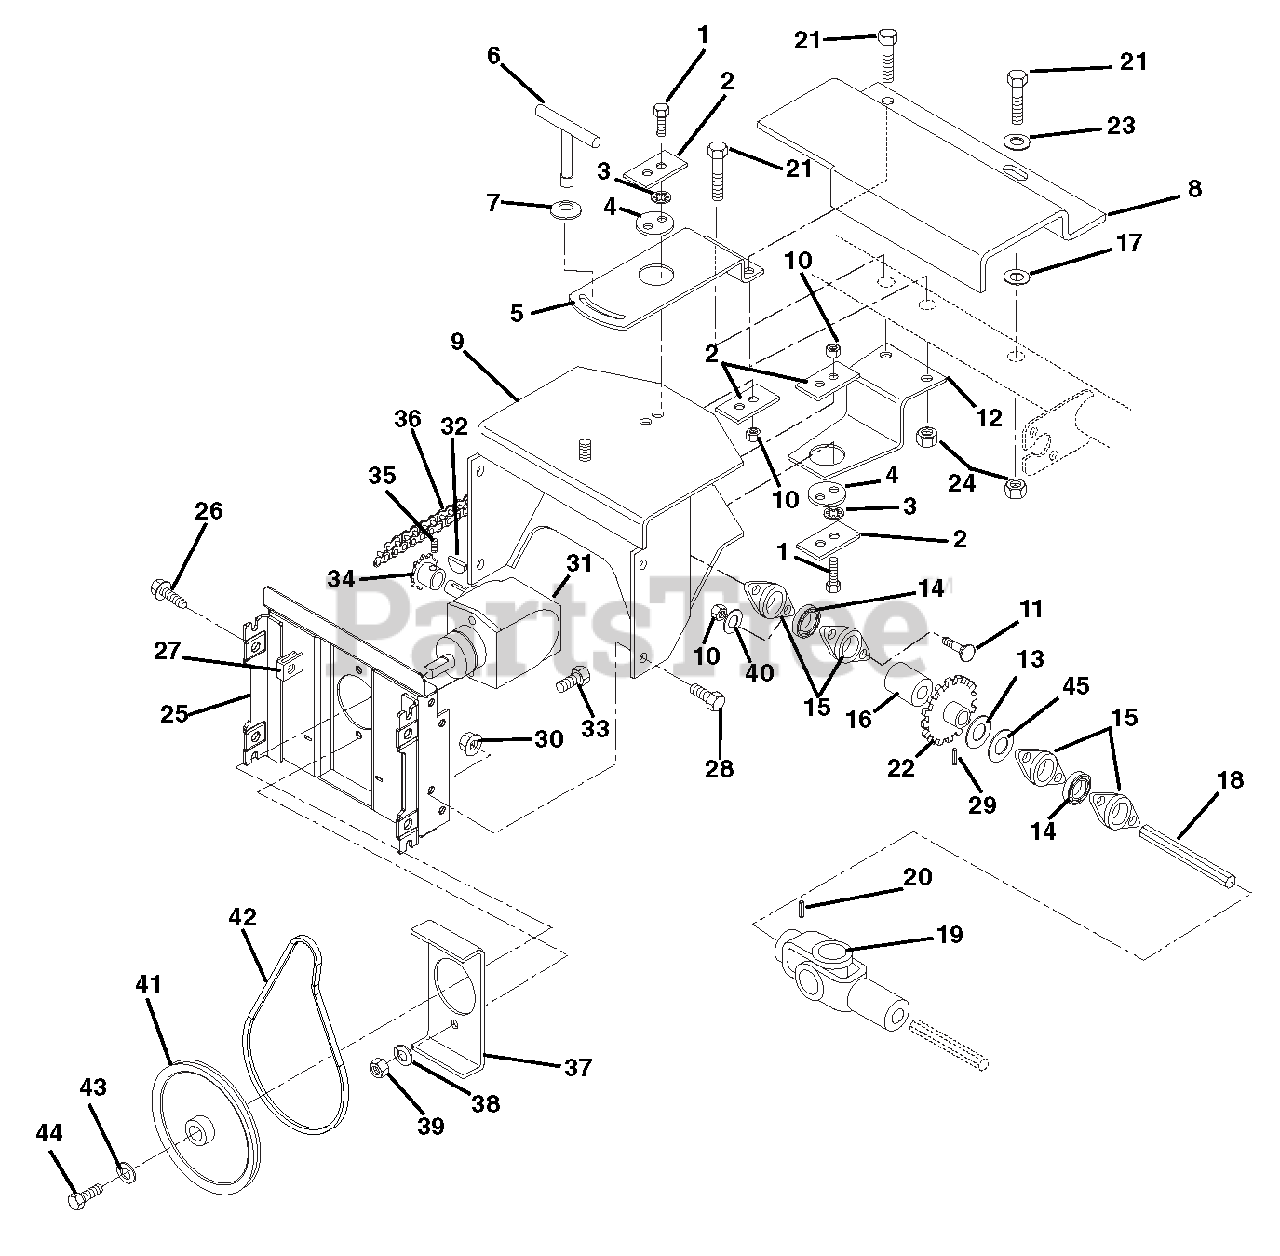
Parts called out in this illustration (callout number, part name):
1	@BLT-HEX .31-18X1.25 GR5 YWZC
2	RETAINER
3	@WSHR-LK-EXT.326X.599X.031YWZC
4	PIVOT CENTER
5	PLATE, TOP MOUNT
6	T-LOCK HANDLE
7	WSHR-BLVL .669X1.535X.138
8	GUARD, SHAFT
9	FRAME, ADAPTOR
10	@NUT-LK-CTR .31-18 YWZC
11	@BLT-RDHDSQNK .31-18X.75 G5YZ
12	PLATE, BOTTOM MOUNT
13	WSHR-FL-STL 1.031X1.625X.188
14	BRG-BALL .884HEXX52MMX1.07
15	BEARING FLANGE
16	SPACER 1.006X1.307X.500
17	WSHR-FL-STL .390X.88X.18 YWZC
19	JOINT, UNIVERSAL
20	PIN-ROLL .188X1.50
21	@BLT-HEX .38-16X3.25 GR5 YWZC
22	SPROCKET
23	@WSHR-FL-STL.406X.812X.065 YWZ
24	@NUT-LK-CTR .38-16 YWZC
25	PLATE, MOUNTING-BROOM
26	BLT-SERHFWH .38-16X.75 YWZC
27	NUT-RTNR .375-16X.37
28	@BLT-HEX .38-16X.75 GR5 YWZC
29	PIN-ROLL .188X1.75
30	@NUT-LK-CTR .38-16 YWZC
31	GEAR BOX ASSEMBLY
32	KEY-WDRF .188X.75X.313 SAE 9
33	@BLT-HEX .38-16X1.25 GR5 YWZC
34	SPROCKET
35	SCR-SET .25-20X.38 SKHCUPNL OH
36	ROLLER CHAIN #41 - 34 PITCHES
37	PLATE, STIFFENER
38	@WSHR-LK .38X.094 REG YWZC
39	@NUT-HEX .38-16 YWZC
40	@WSHR-FL-STL.38X.875X.083 YWZC
41	PULLEY, 4L W/HUB - .87 X 8.5
42	V-BELT, 4L-RAW EDGE
43	WSHR-LK .312X.097 HVY YWZC
44	BLT-HEX .31-24X.75 YWZC GR5
45	WSHR-FL-STL 1.03X1.31X.105
